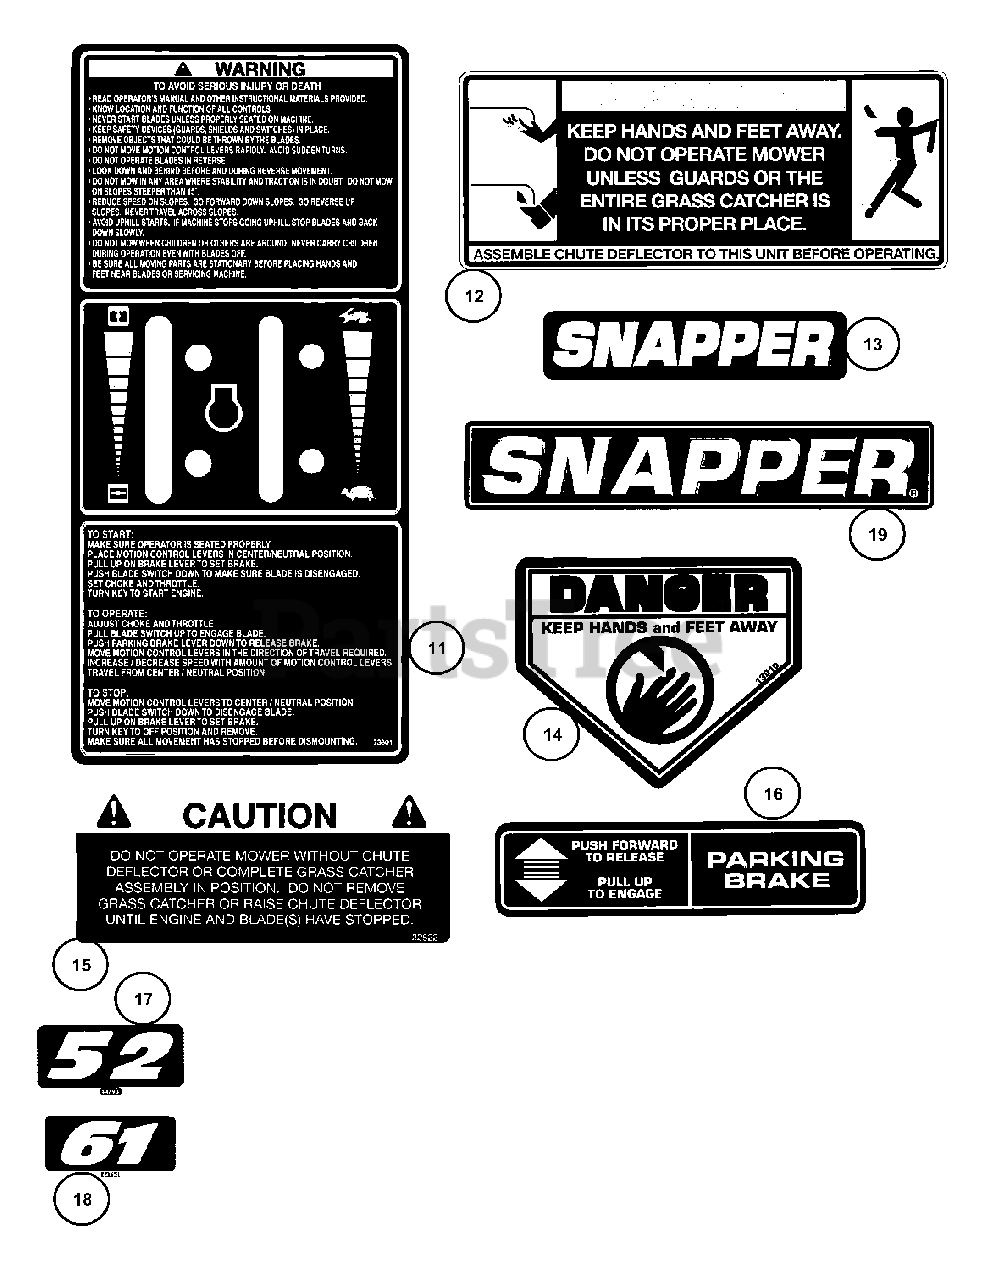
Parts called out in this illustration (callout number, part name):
11	DECAL, Throttle/Choke
12	DECAL, Danger Guard/Catcher
13	DECAL, Nameplate Snapper
14	DECAL, Warning (Cut-Finger)
15	DECAL, Warning
16	DECAL, Park Brake
17	DECAL, Deck Size (52" only)
18	DECAL, Deck Size (61" only)
19	DECAL, Snapper (3D)
